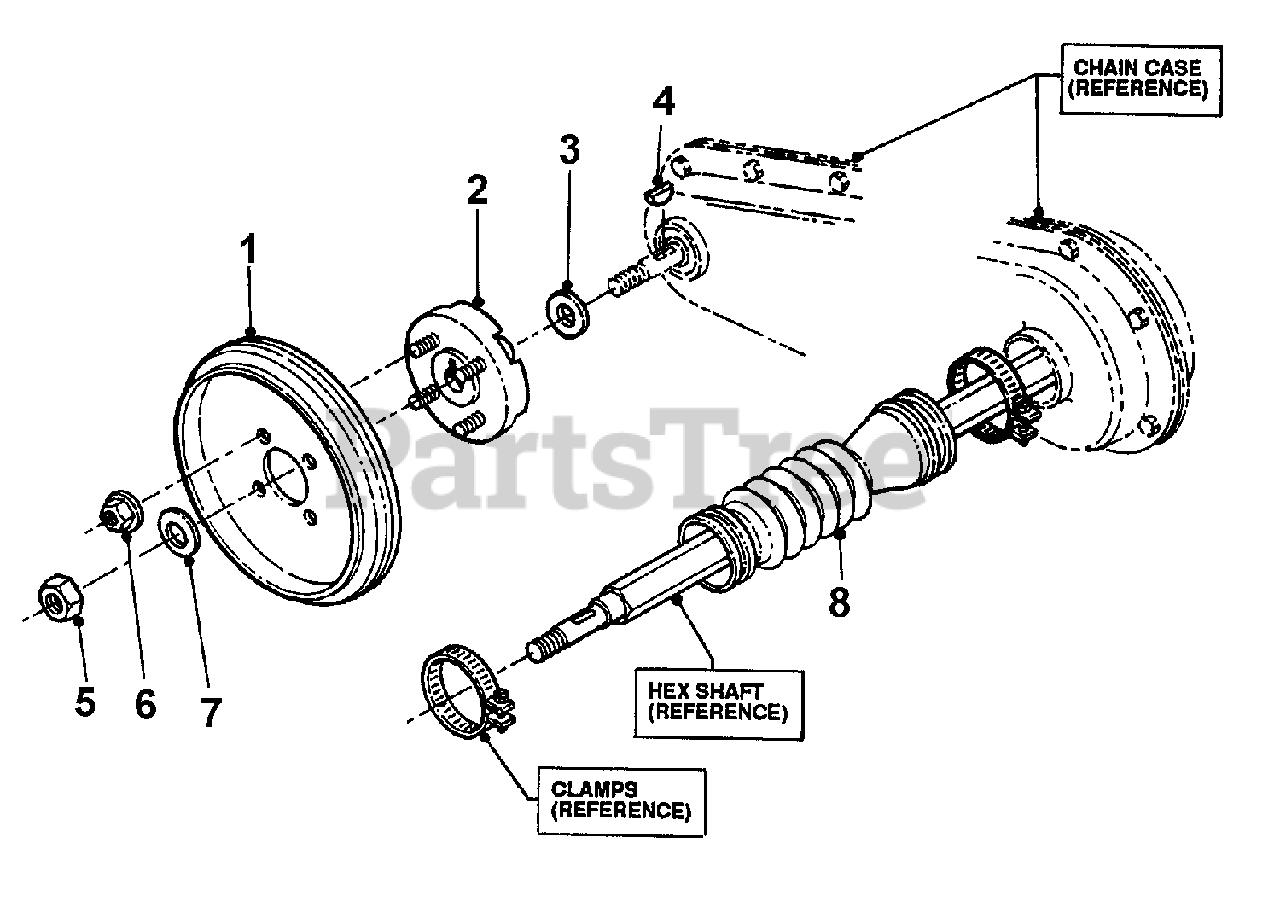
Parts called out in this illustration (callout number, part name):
1	DRIVEN DISC, MID DUTY
2	HUB ASSY.
3	FW, 5/16 X 7/8 X .083 ZP
4	KEY, WOODRUFF, #304
5	HLN, 3/8F GR.C ZP
6	HFLN, 1/4C YZ
7	WASHER, BELLEVILLE 3/8" ID x 3/4" OD
8	COVER, SHAFT
